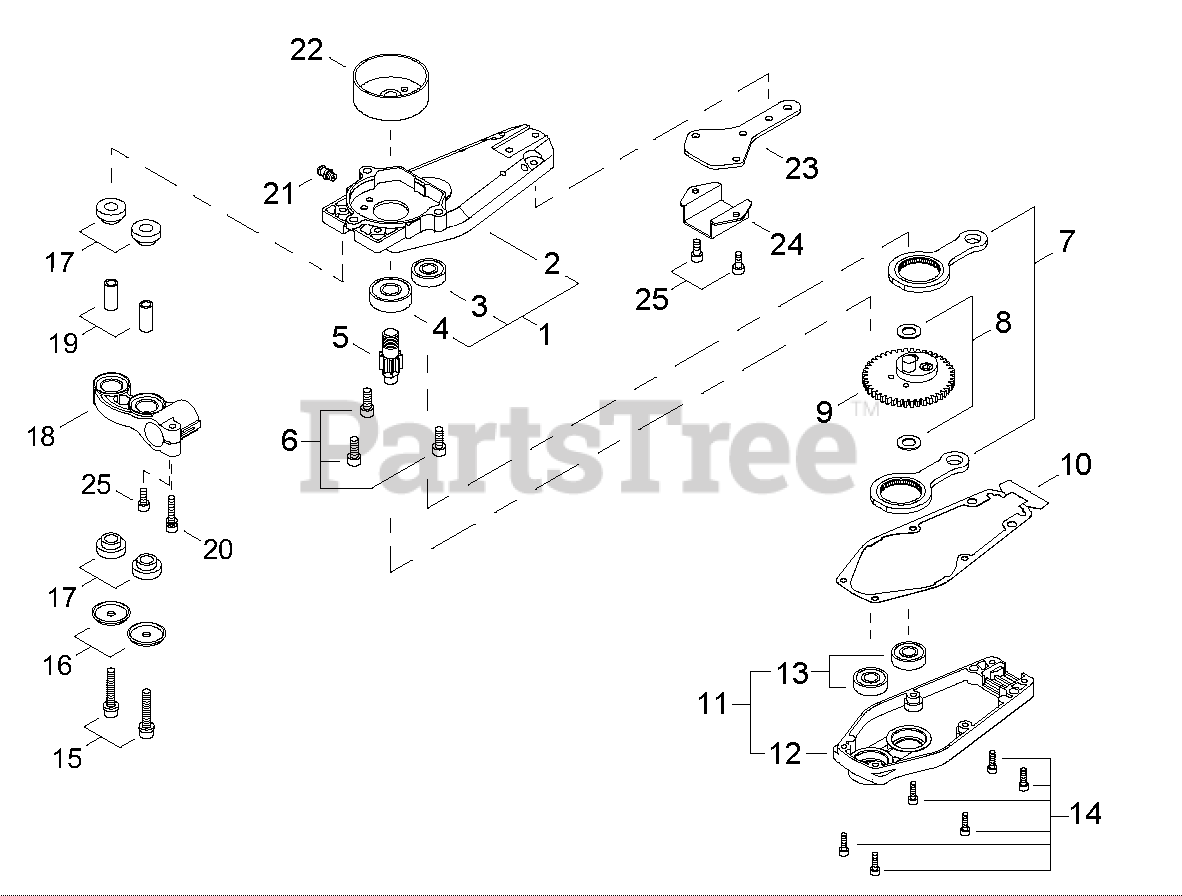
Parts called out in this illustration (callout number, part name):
1	GEAR CASE HOUSING ASSY
2	HOUSING, GEAR CASE
3	BEARING, BALL 6000ZZ
4	BEARING, BALL 6201
5	SHAFT, PINION
6	BOLT 6×16
8	WASHER 10
9	CAM GEAR ASSY
10	GASKET, GEAR CASE
11	COVER ASSY, GEAR CASE
12	COVER, GEAR CASE
13	BEARING, BALL 6000ZZ
14	BOLT 4×14
15	BOLT M6×35
16	WASHER 6
17	CUSHION
18	MOUNT, HANDLE
19	COLLAR 6
20	BOLT M5×25
21	FITTING, GREASE
22	DRUM, CLUTCH
23	PLATE, EYE
24	GUIDE, BLADE
25	BOLT 5×12
